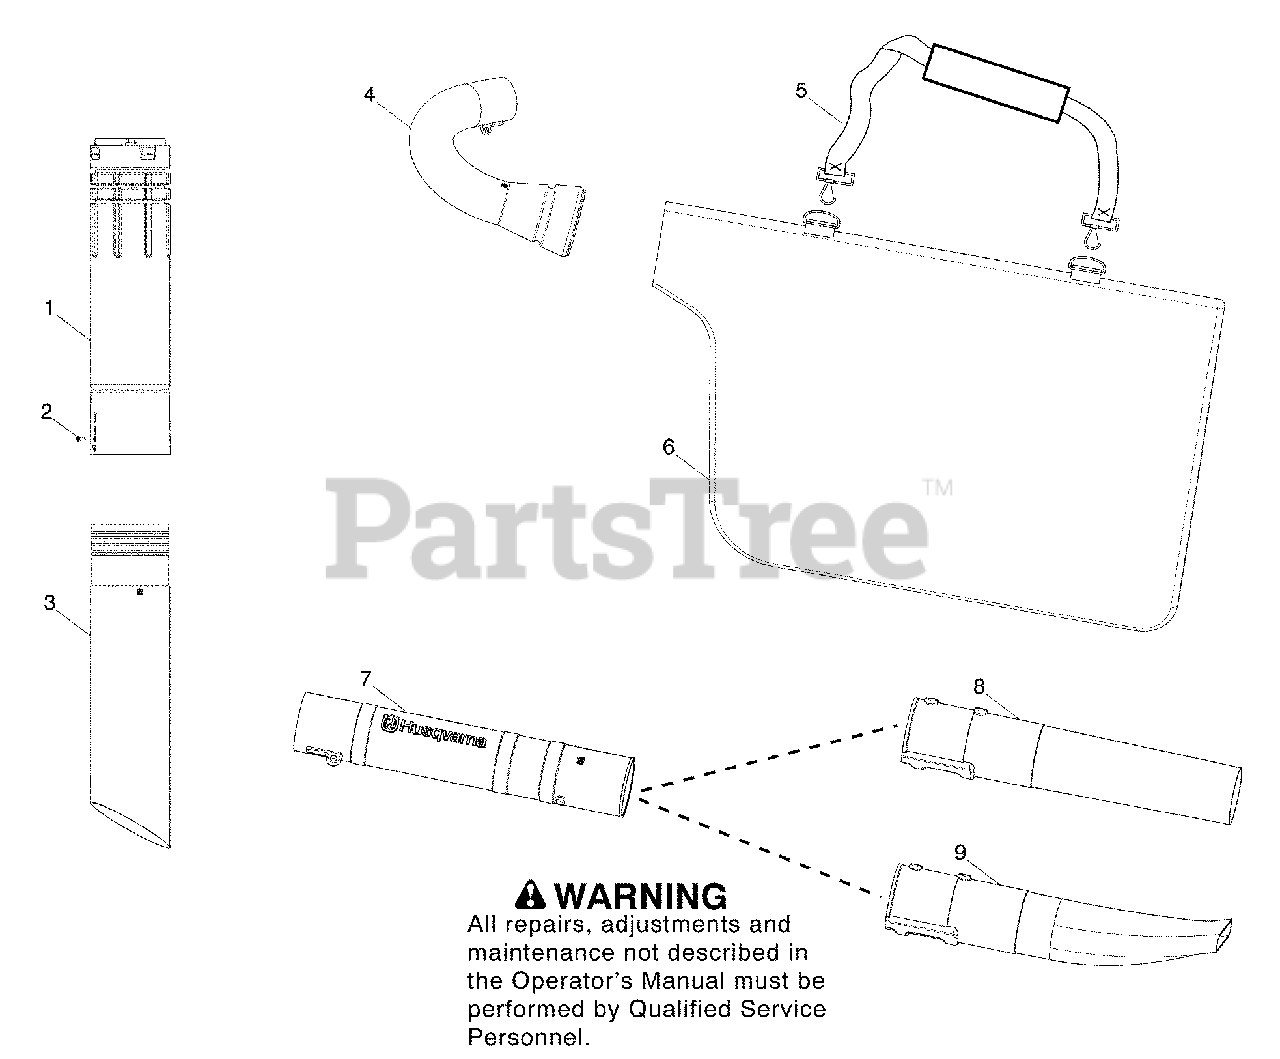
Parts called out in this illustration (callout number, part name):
1	Assy - Upper vac tube with adapter
3	Tube - Lower vac
4	Elbow - Vac
5	Strap - Carrying
6	Assy - Vac bag
7	Assy - Tube - upper blower w/barrier
8	Tube - Lower blower
9	Tube - Lower blower
